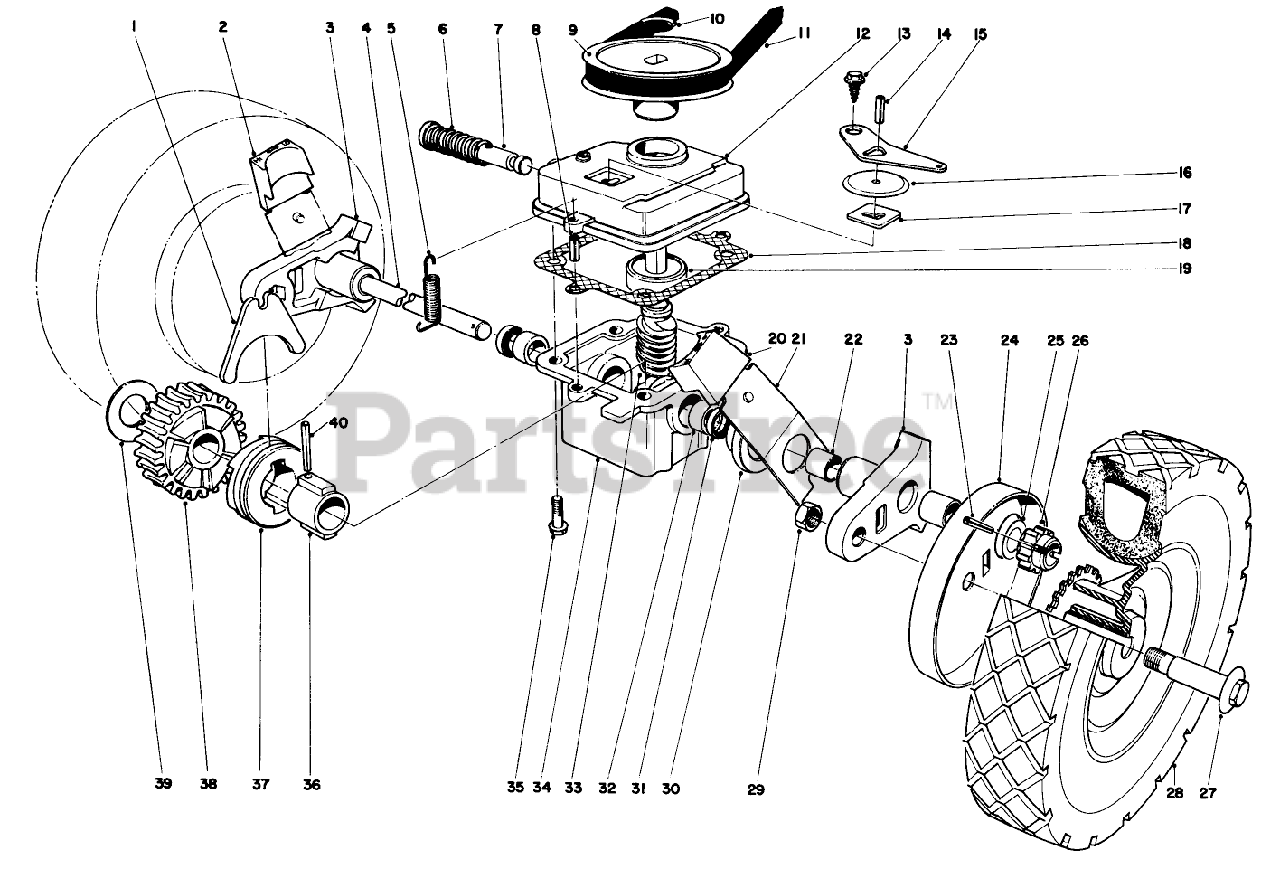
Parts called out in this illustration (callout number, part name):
1	SHIFTER FORK
2	Arm Knob
3	Pivot Arm (Incl. Ref. No. 22)
4	Drive Shaft
5	TENSION SPRING
6	SPRING
7	Shift Rod
8	3/16 X 1/2 ROLL PIN
9	PULLEY
10	PUSH-ON 93-3236
11	V BELT
12	GEAR CASE COVER
13	Screw
14	PIN-ROLL
15	SHIFTER ARM
16	TRANS DUST COVER
17	LATCH PLATE
18	GASKET
19	Bearing
20	Arm Knob
21	Spring Arm
22	BUSHING
23	PIN-GROOVED
24	WHEEL COVER
25	WASHER-THRUST
26	Pinion
28	Wheel & Tire
29	Nut
30	End Cap
31	Seal
32	Bushing
33	WORM SHAFT
34	Gear Case
35	Screw
36	SLEEVE
37	CLUTCH JAW
39	THRUST WASHER
40	COIL PIN
